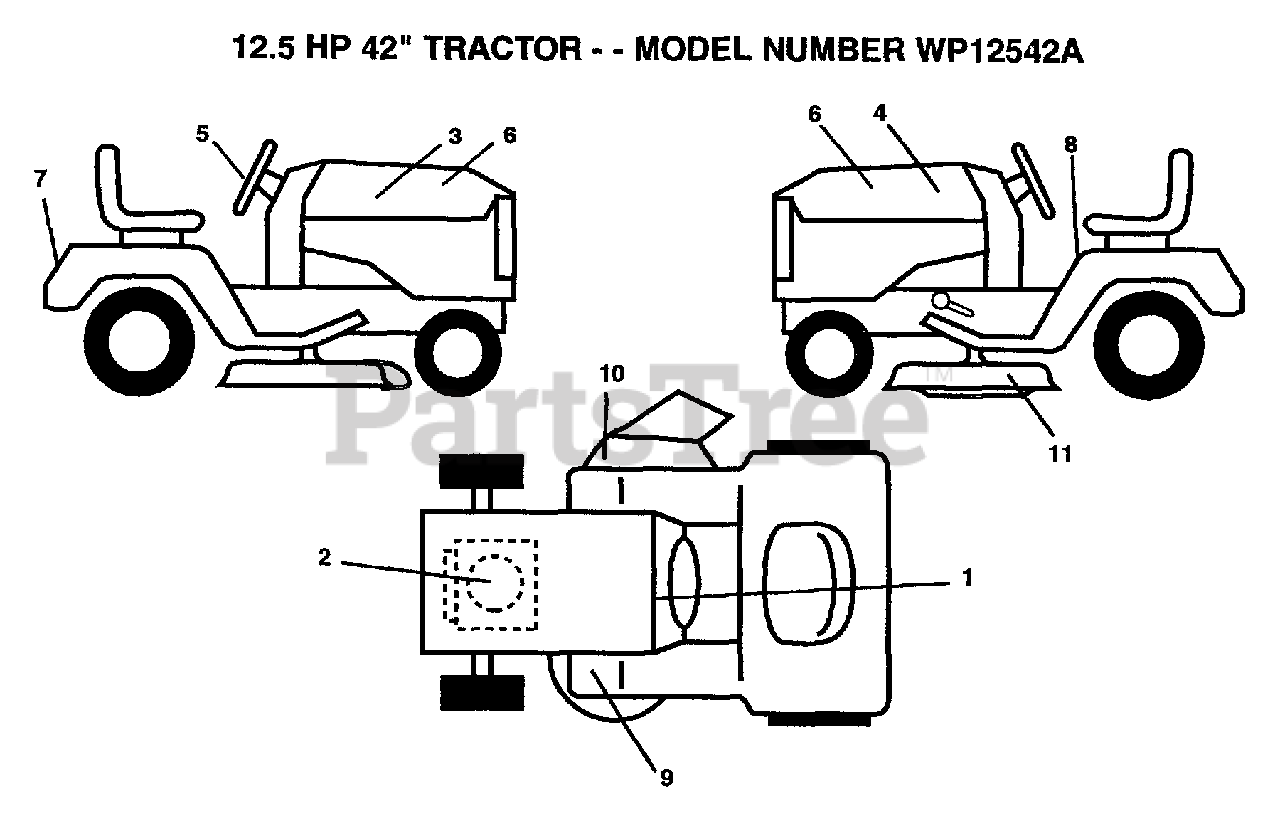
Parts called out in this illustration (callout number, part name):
3	DECAL, HOOD RH
4	DECAL.HOOD.LH
5	DECAL, INSERT
7	DECAL, FENDER WINSTON PRO
8	DECAL
10	DECAL WARING
11	DECAL INSTRUCTION CAUTION
